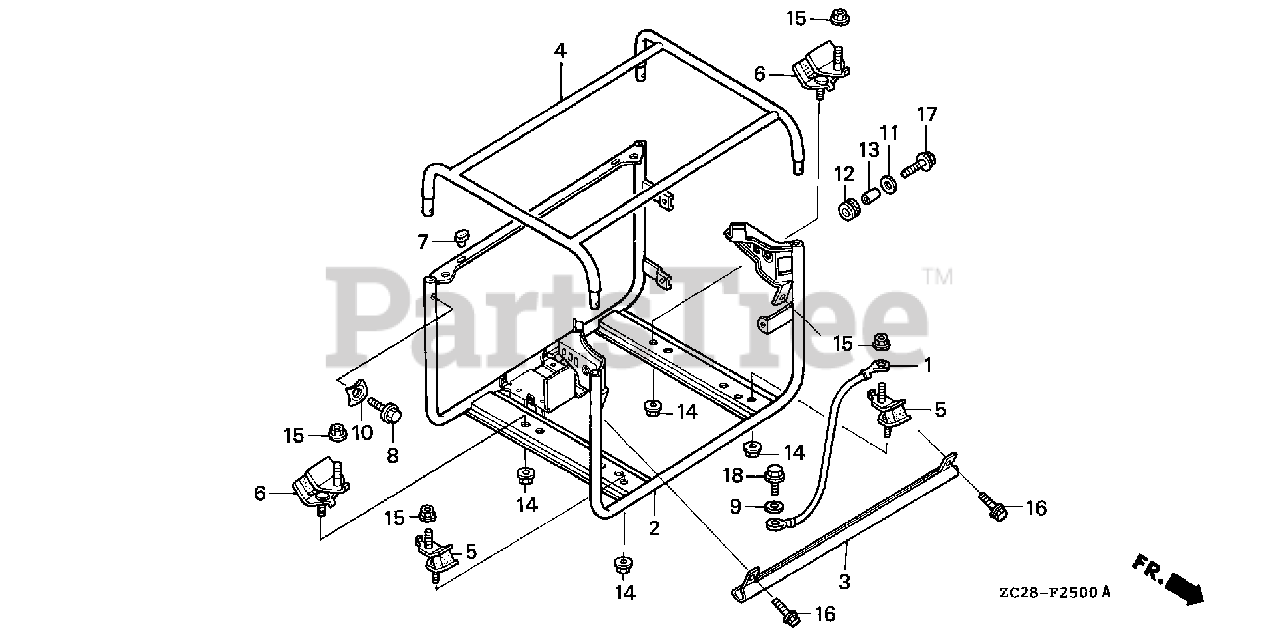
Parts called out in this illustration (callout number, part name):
1	CABLE, GROUND
2	FRAME (LOWER) *NH105* (MAT BLACK)
3	CHANNEL, FR. *NH105* (MAT BLACK)
4	FRAME (UPPER) *NH105* (MAT BLACK)
5	RUBBER (LOWER)
6	RUBBER (LOWER)
7	STOPPER, DISCHARGE GUARD
8	BOLT, FLANGE (8X16)
9	WASHER, LOCK (6MM)
10	WASHER, FRAME JOINT
11	WASHER, FLAT (20MM)
12	RUBBER, CONTROL BOX
13	COLLAR, CONTROL BOX
14	NUT, FLANGE (8MM)
15	NUT, FLANGE (10MM)
16	BOLT, FLANGE (6X12)
17	BOLT, FLANGE (6X18)
17	BOLT-WASHER (6X20)
18	BOLT, FLANGE (6X10)
